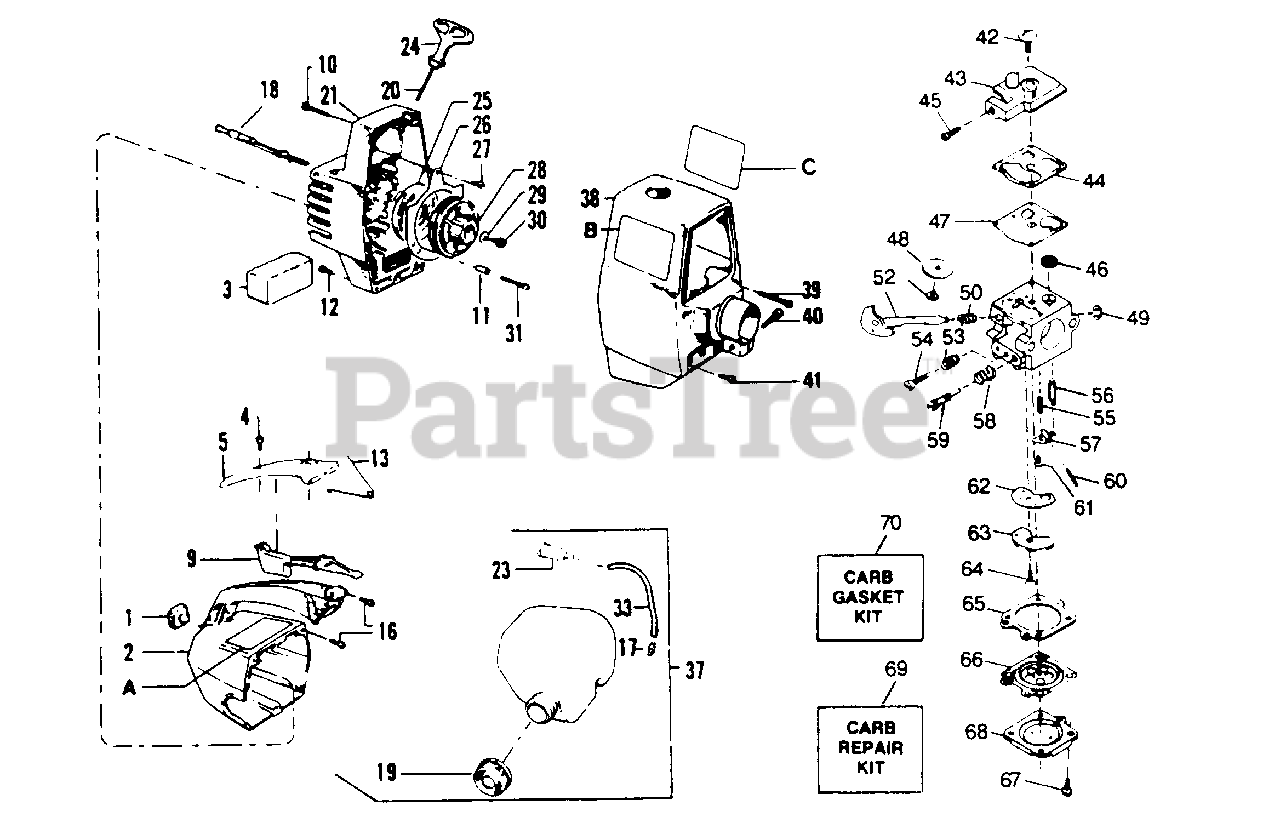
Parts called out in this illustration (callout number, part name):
1	Bumper-Fuel Tank Housing
2	Handle & Fuel Tank Housing
3	Air Filter
4	Screw-#8-16x3/4-Pan Hd. Handle Cover
5	Handle Cover
9	Throttle Trigger
10	Screw-# 10-24x1-1/2"-Sems-Fan Housing Top
11	Air Baffle Spacer
12	Screw-# 10-24x5/8"-Sems Fan Housing-Bottom
13	Spring-Trigger
16	Screw-# 10-14x3/4"-Pan Head-Fan Hag. to Handle & Fuel Tank
17	Fuel Line Fitting
18	Choke Knob
19	Fuel Cap Assembly (incl. O-Ring)
20	Rope Kit
21	Fan Housing Kit
23	Fuel Pick-up Assembly
24	Handle Rope Kit
25	Starter Recoil Spring
26	Air Baffle
27	Screw-# 10-14x3/8"-Pan Hd-Air Baffle
28	Starter Pulley
29	Washer-Starter Pulley
30	Screw-# 10x3/4" Hex Washer Hd.-Starter Pulley
31	Screw-# 10-14x1-3/16" Air Baffle/Pump Mounting
33	Line Kit
37	Fuel Tank Assembly (inc. 17-19,23,33)
39	Screw- # 10-24 x 1-1/3"-Fil Hd.-Shroud (Top)
41	Screw- # 10-24x5/8"-Fil Hd.-Shroud Bottom
42	Screw-Pump Cover
43	Pump Cover Ass'y (incl #4)
44	Gasket-Pump
45	Screw-Idle Adjustment
46	Screen-Inlet
47	Diaphragm-Pump
51	Screw-Throttle Valve
52	Shaft Assembly Throttle
53	Spring-Idle Needle
54	Needle-Idle
55	Spring-Metering Lever
56	Valve-Inlet Needle
57	Lever-Metering
58	Spring-Hi Speed Needle
59	Needle-Hi Speed
60	Pin-Metering Lever
61	Screw-Metering Lever Pin
62	Gasket-Circuit Plate
63	Plate-Circuit
64	Screw-Circuit Plate
65	Gasket-Metering Diaphragm
66	Diaphragm Assembly-Metering
67	Screw Assembly-Metering Cover & Throttle Shaft Clip
68	Cover-Metering Diaphragm
69	Kit-Carb Kwik Repair
70	Kit-Carb Gasket/Diaphragm
A	Start Inst. Fr./Eng.
B	Model No. (R)
C	Model No. (L)
